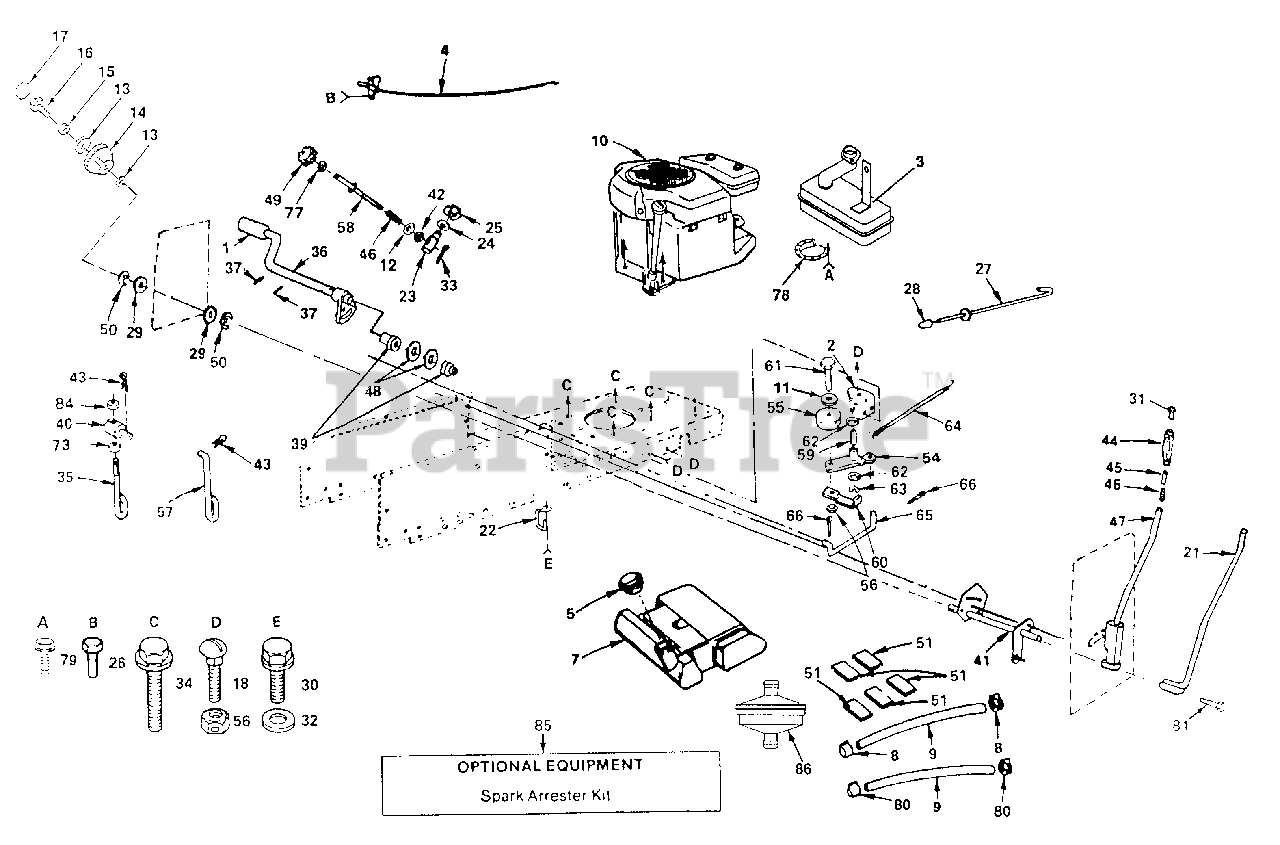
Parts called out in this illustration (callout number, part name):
1	Pedal Cover
2	Bracket Assembly, Clutch
3	Muffler
4	Control, Throttle/Choke
5	Fuel Cap Assembly
7	Tank, Fuel
8	Hose Clamp
9	Fuel Line
10	Engine 12.5 HP
11	Washer, 13/32 x 13/16 x 16 Ga.
12	Washer 13/32 x 5/8 x 16 Ga.
13	Washer 11/32 x 1 1/2 x 10 Ga.
14	Scale, Height Indicator
15	Washer, Lock Hvy. Hel. Spring
16	Bolt, Fin Hex 5/16 - 18 UNC x 1
17	Plug, Hole
18	Bolt, Carriage, 3/8-16 x 3/4
21	Rod Assembly, Lever
22	Retainer, Belt, Chassis, L.H.
23	Trunnion, Stop, Depth
24	Washer, 15/32 x 3/4 x 16 Ga.
26	Screw, Hex Washer Hd Thd. Cutting 1/4-20 x 5/8
27	Rod, Brake, Park
28	Plunger Cap
29	Washer, 29/32 x 1 - 1/4 x 16 Ga
30	Screw, Hex Washer Thd Rolling 3/8- 1 6 x 3/4
31	Button, Plunger
32	Washer, 13/32 x 13/16 x 12 Ga.
33	Cotter Pin, 3/32 x 1/2
34	Screw, Hex Washer Hd. Thd. Rolling M8 x 1.25 x 25 MM
35	Lift Link, Adjustable
36	Shaft Asm. Pedal Foot
37	Roll Pin 3/16 x 1
39	Bearing, Nylon
40	Trunnion, Lift
41	Shaft Assembly, Lift
42	Nut, Hex Special
43	Retainer Spring
44	Grip, Handle
45	Plunger, Lever, Hand
46	Spring
47	Lever Assembly, Hand Kit
48	Washer, 21/32 x 1.00 x 16 Ga.
49	Handle, Adjust, Lift
51	Pad, Spacer
54	Arm Assembly, Idler
55	Pulley, Idler
56	Locknut, 3/8 - 16
57	Link, Lift
58	Rod, Adjust, Lift
60	Retainer Belt
61	Bolt, Hex 3/8 - 16 x 1-1/2
62	Washer, Hardened
64	Spring, Return, Clutch
65	Link, Clutch
66	Pin, Cotter 1/8 x 3/4
73	Nut, Hex Jam 7/16 - 20
77	Nut, Hex Jam 3/8 - 16
78	Deflector, Muffler
79	Screw, Spiderlock Hex Hd. #8 x 1/2
80	Clamp, Hose
81	Bolt, Hex Hd. 3/8 - 16 x 1-1/2
84	Nut, Crownlock 7/16-20
85	Spark Arrestor Kit
86	Filter, Fuel
